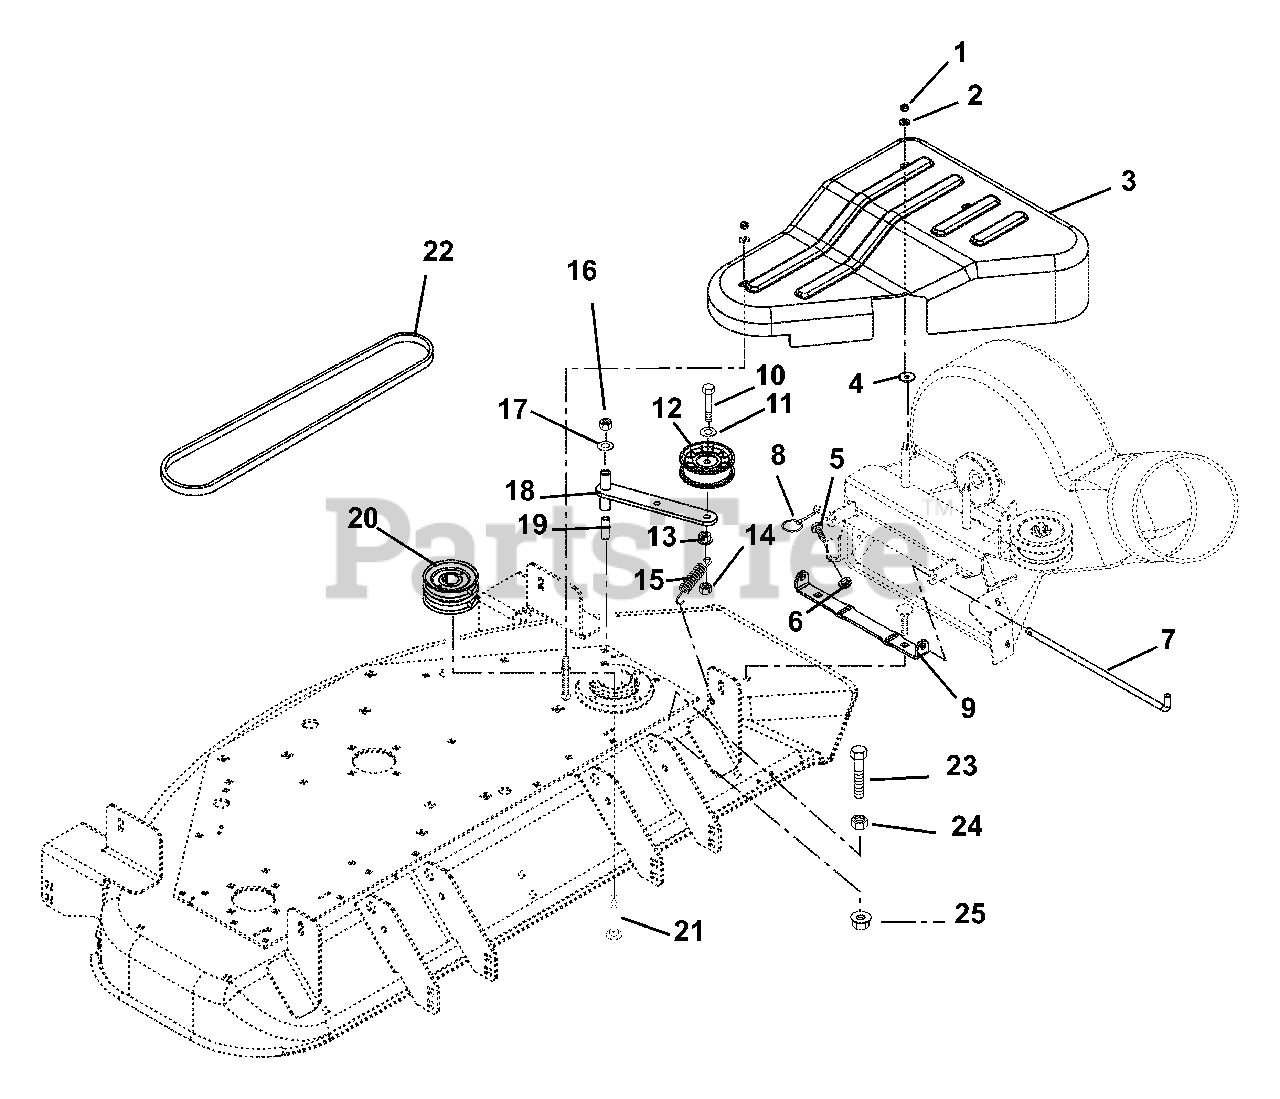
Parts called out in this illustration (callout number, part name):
1	Nut-Lock-Nylon .25-20
2	Washer-Flat-Steel .281 x .62 x.065
3	Guard-Belt Bagger 50"
4	Washer-Flat-Steel .281 x 1.00 x.063
4	(Gravely Part Number)
5	Screw-Machine 10-24 x .50 Hex Washer Head
6	Nut-Locking-Nylon 10-24 with Insert
7	Rod-Mounting
8	Pin-Klik 1.00 x .188 x 1.25
8	(Gravely Part Number)
9	Bracket, Chute Pivot
10	Bolt-Hex .38-16 x 2.50 Grade 5
11	Washer-Flat-Steel .438 x 1.00 x.083
12	Idler-Flat 3.50 x .38
13	Nut-Flange .375-16
14	Nut-Locking-Nylon .38-16
15	Spring-Tension .069 x .62 x 3.50
15	(Gravely Part Number)
16	Nut-Locking-Nylon .312-18
17	Washer-Flat-Steel .328 x 1.00 x.094
18	Bracket-Tension Arm
19	Spacer .344 x .613 x 1.780
20	Pulley-Double V, 3.50 x 1.004
21	Bolt-Round Head Square Neck.31-18 x 2.75
22	V-Belt A-Section 28.50 x .531
23	Bolt-Hex .38-16 x 1.75 Grade 5
24	Nut-Hex .38-16
25	Nut-Locking-Top-Flange .38-16
